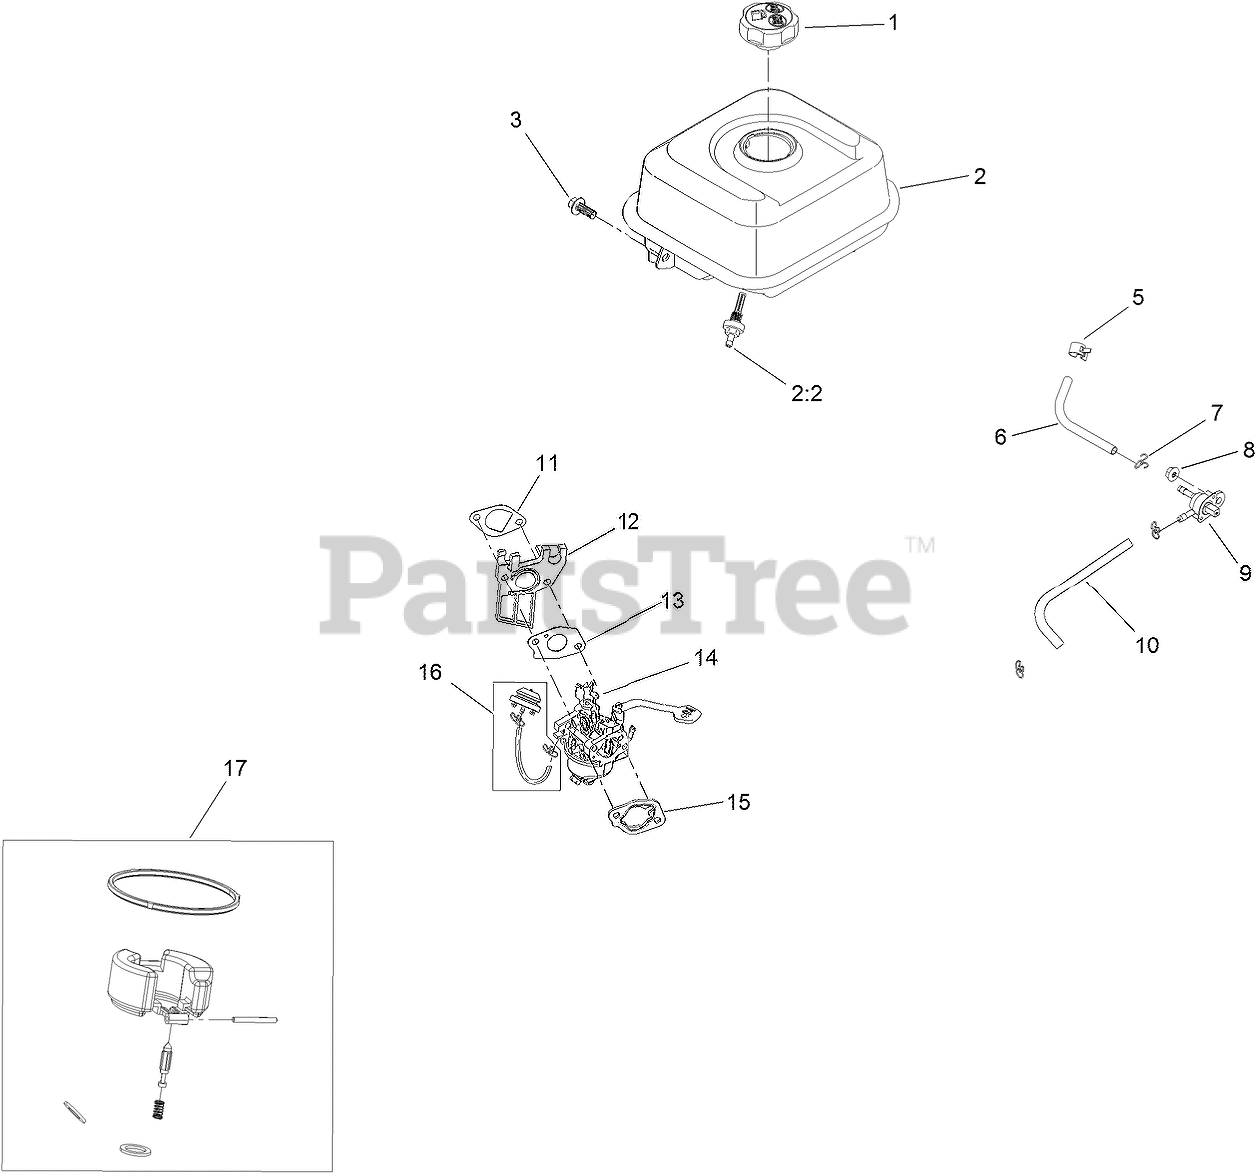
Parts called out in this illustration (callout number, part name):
1	CAP-FUEL
2	FUEL TANK AND FILTER ASM
2:2	FILTER-FUEL
3	SCREW-HHF
5	CLAMP-HOSE
6	HOSE-FUEL, FORMED
7	CLAMP-HOSE
8	NUT-FLANGE
9	VALVE-FUEL
10	HOSE-FUEL, FORMED
11	GASKET-CARBURETOR
12	INSULATOR-CARBURETOR
13	GASKET-CARBURETOR
14	CARBURETOR ASM
15	GASKET-CARBURETOR
16	PRIMER KIT
17	INTERNAL CARB SERVICE KIT
